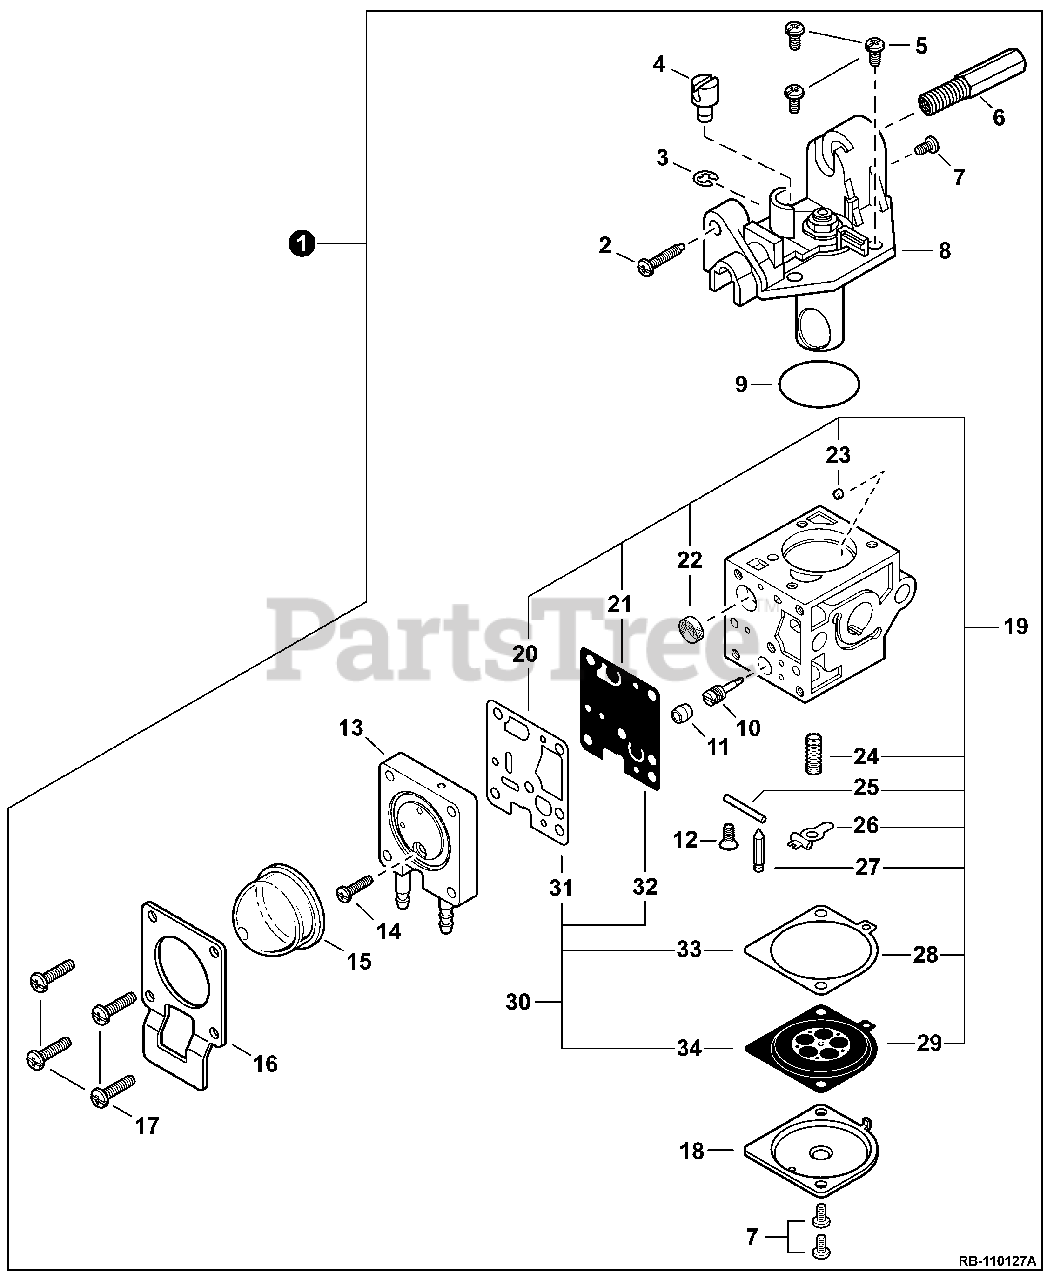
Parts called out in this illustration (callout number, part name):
1	CARBURETOR RB-110127A
2	SCREW, IDLE ADJUST
6	ADJUSTER, THROTTLE CABLE
8	COVER ASSY, ROTOR
10	NEEDLE, HIGH SPEED
11	CAP, LIMITER
13	BODY ASSY, PURGE
15	BULB, PURGE
16	RETAINER, PURGE BULB
18	COVER, METERING DIAPHRAGM
19	REPAIR KIT, CARBURETOR
20	GASKET, PUMP
21	DIAPHRAGM, PUMP
22	SCREEN, FUEL INLET
23	GUIDE, ROLLER
24	SPRING, METERING LEVER
25	PIN, METERING LEVER
26	LEVER, METERING
27	VALVE, INLET NEEDLE
28	GASKET, METERING DIAPHRAGM
29	DIAPHRAGM, METERING
30	GASKET / DIAPHRAGM KIT
31	GASKET, PUMP
32	DIAPHRAGM, PUMP
33	GASKET, METERING DIAPHRAGM
34	DIAPHRAGM, METERING
